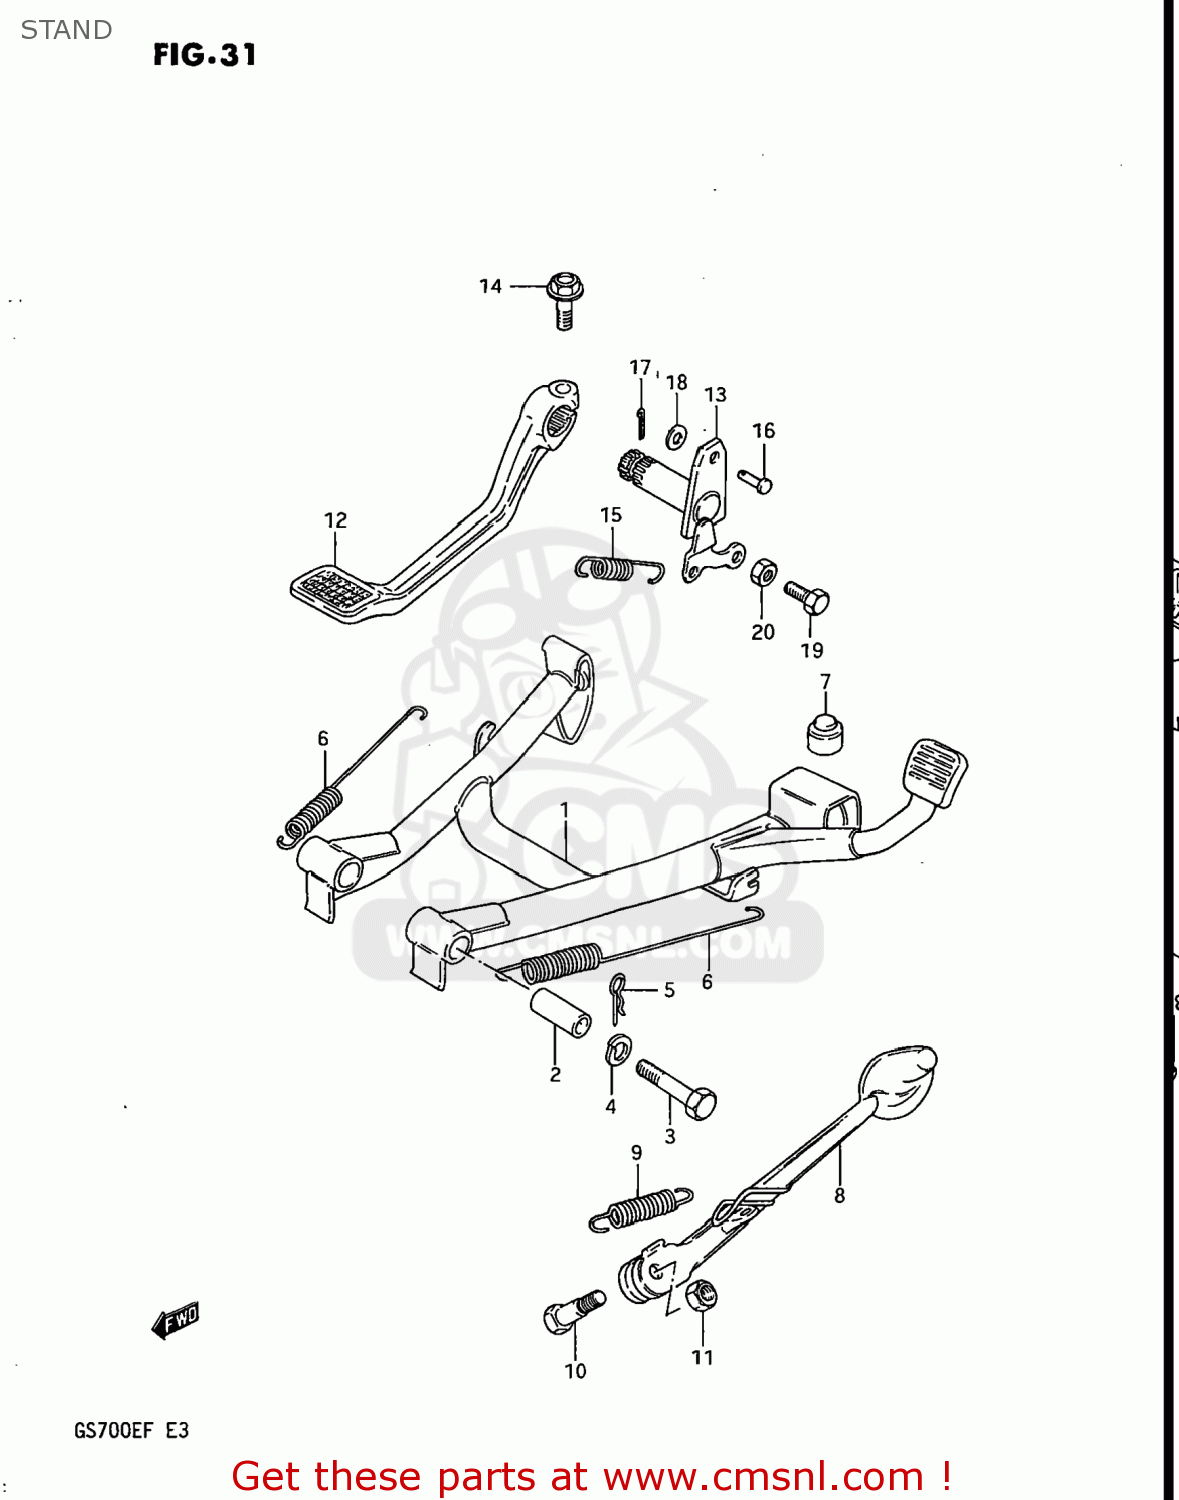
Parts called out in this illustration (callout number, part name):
1	STAND,CENTER
2	SPACER(10X16X38.8)
3	BOLT
4	LOCK WASHER
5	CLIP
6	SPRING
7	CUSHION
8	STAND,SIDE
9	SPRING
10	BOLT(10X32)
11	NUTM10X1.25X8
12	PEDAL,BRAKE
13	ARM,BRAKE PEDAL
14	BOLT
15	SPRING
16	PIN
17	PIN
18	WASHER
19	BOLT
20	NUT
